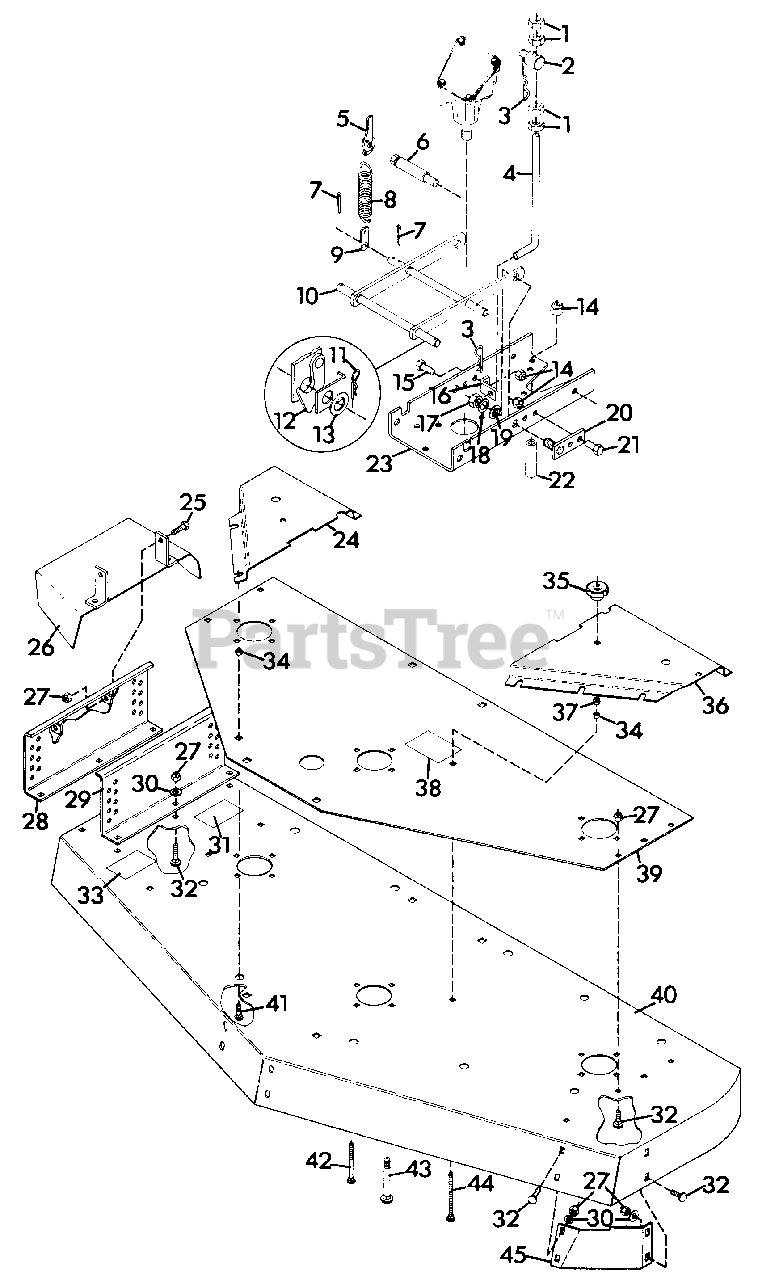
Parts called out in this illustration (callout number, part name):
1	Nut-Jam .50-13 Grade 2
2	Pivot, Mower Lift
3	Pin-Cotter .12 x 2.0
4	Rod, Lift
5	Assembly, Spring Latch Right Hand
6	Latch, Pin
7	Pin-Cotter .12 x 1.25
8	Spring-Lift .244 x 1.75 x 7.6
9	Strap
10	Weldment, Pivot Arm
11	Pin-Hair-Internal .15 x 2.937
12	Keeper, Mower Pivot
13	Washer-Flat-Steel .813 x 1.370 x .100
14	Nut-Locking-Nylon .50-13 Grade 5
15	Bolt-Hex .50-13 x 1.75
16	Bracket, Lift
17	Nut-Locking .750-10
18	Bearing-Needle-Thrust .752 x 1.24 x .031
19	Bushing-Flange .762 x 1.0 x .580 x 1.48
20	Weldment, Pivot Anchor
21	Bolt-Hex .50-13 x 1.50 Grade 5
22	Spacer .562 x .855 x 2.18
23	Plate, Support
24	Cover, Belt Right Hand
25	Bolt-Hex .38-16 x 1.25 Grade 5
26	Weldment, Discharge Chute
27	Nut-Locking-Nylon .375-16 Grade 2
28	Weldment, 60" Hanger
29	Hanger, Left Hand
30	Washer-Flat-Steel .406 x .812 x .065
31	Decal, Danger Hand
32	Bolt-Round Head Square Neck .38-16 x 1.0
33	Decal, Warning Eye
34	Nut-Locking-Center .50-20
35	Knob
36	Cover, Belt Left Hand
37	Nut-Locking-Nylon .312-18 Grade 2
38	Decal, Belt Diagram
39	Plate, Support
40	Weldment, 60" Mower
41	Bolt-Round Head Square Neck .31-18 x 1.0
42	Bolt-Round Head Square Neck .31-18 x 3.5
43	Bolt-Round Head Square Neck .50-16 x 3.50
44	Bolt-Round Head Square Neck .31-18 x 4.0
45	Baffle, Front
